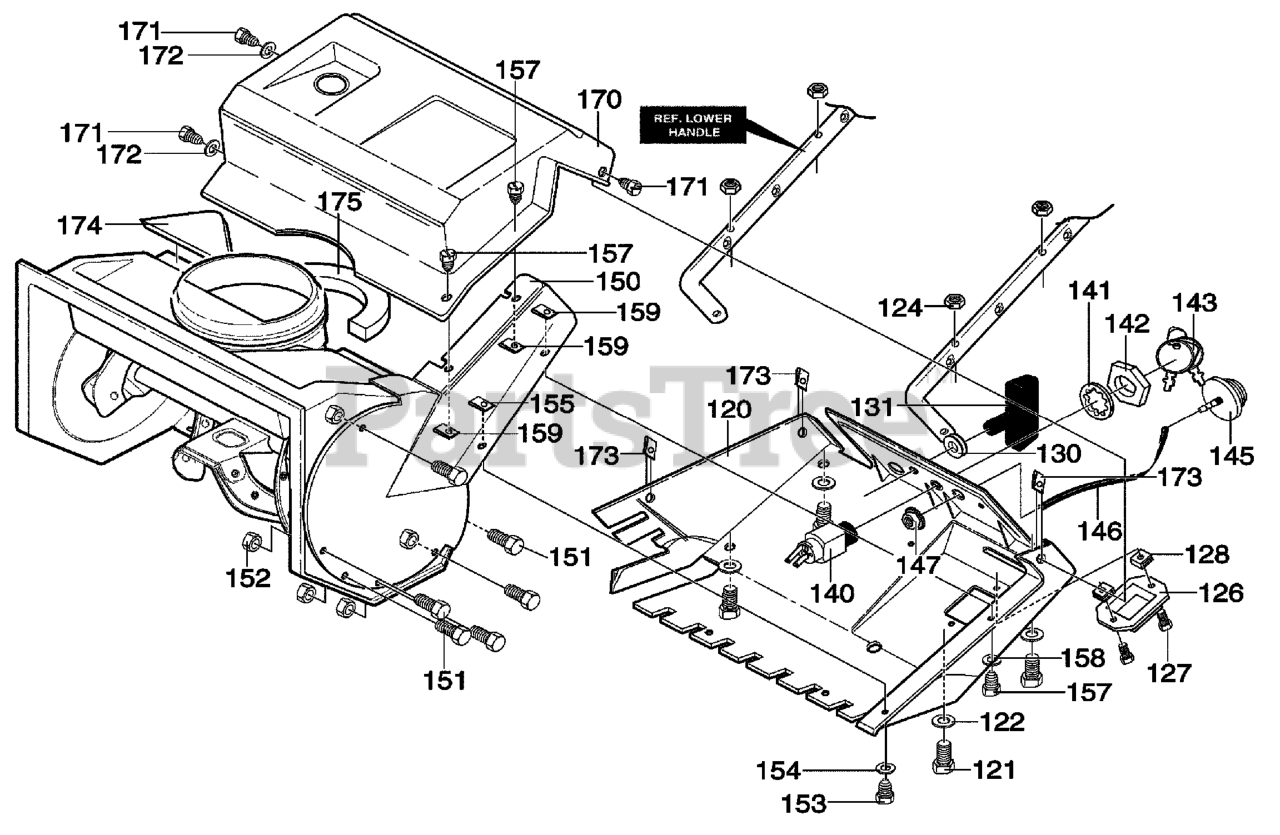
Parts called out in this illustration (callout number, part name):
120	COVER, BOTTOM
121	SCREW, 1/4-20X1.25
122	WASHER, FLAT
124	NUT, 1/4-20
126	COVER, CARB
127	SCREW, 1/4-14X.75
128	NUT, 1/4-10 SPEED J TYPE
130	GROMMET & WASHER, ROPE GUIDE
131	KNOB, STAND TEE
140	SWITCH, IGNITION
141	WSHER
142	NUT, 5/8-32 ACC
143	2 KEYS & RING
145	PRIMER, ENGINE
146	HOSE, PRIMER
147	NUT, 1/4-20
150	COVER, BELT
151	SCREW, 10-24X.50
152	NUT, #10-24
153	SCREW, 1/4-20X.50
154	WASHER, FLAT
155	NUT, 1/4-20
157	SCREW, 1/4-14X.75
158	WASHER, FLAT
159	NUT, 1/4-20
170	COVER, TOP
171	SCREW, 1/4-14X.75
173	NUT, 1/4-10
174	SEAL, STRIP
175	SEAL, STRIP CHUTE & GAS SEAL
